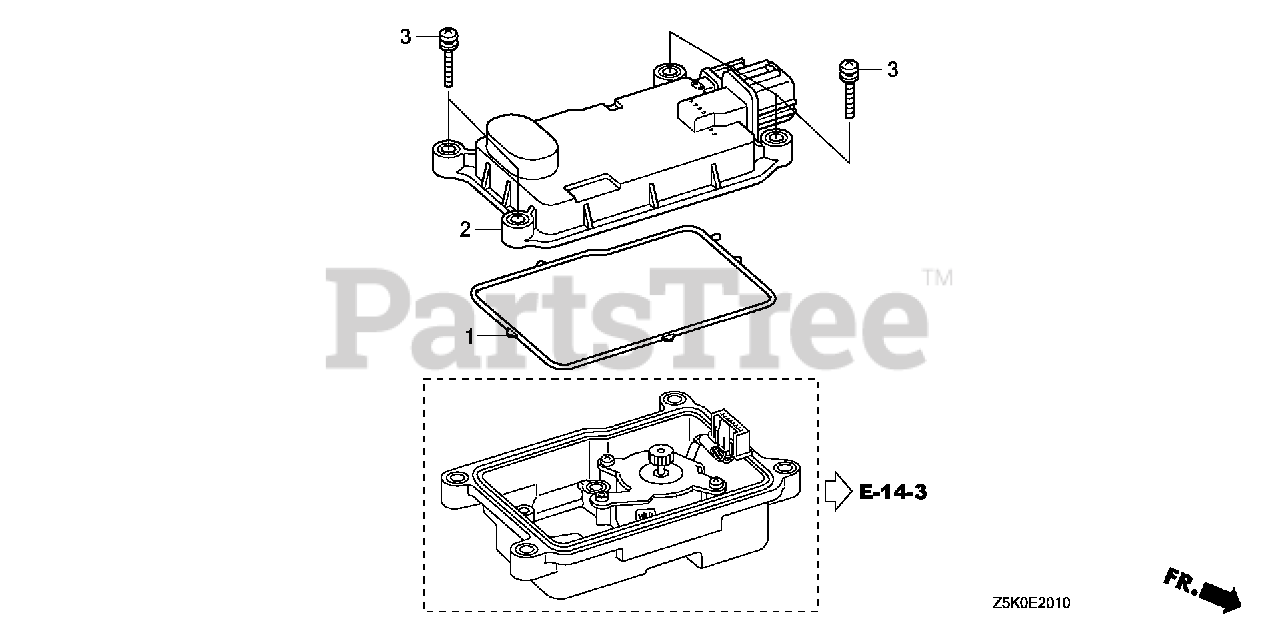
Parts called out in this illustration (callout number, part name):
1	SEAL, ELECTRONIC CONTROL UNIT COVER
2	CONTROL UNIT, ELECTRONIC
3	SCREW-WASHER (4X20)
